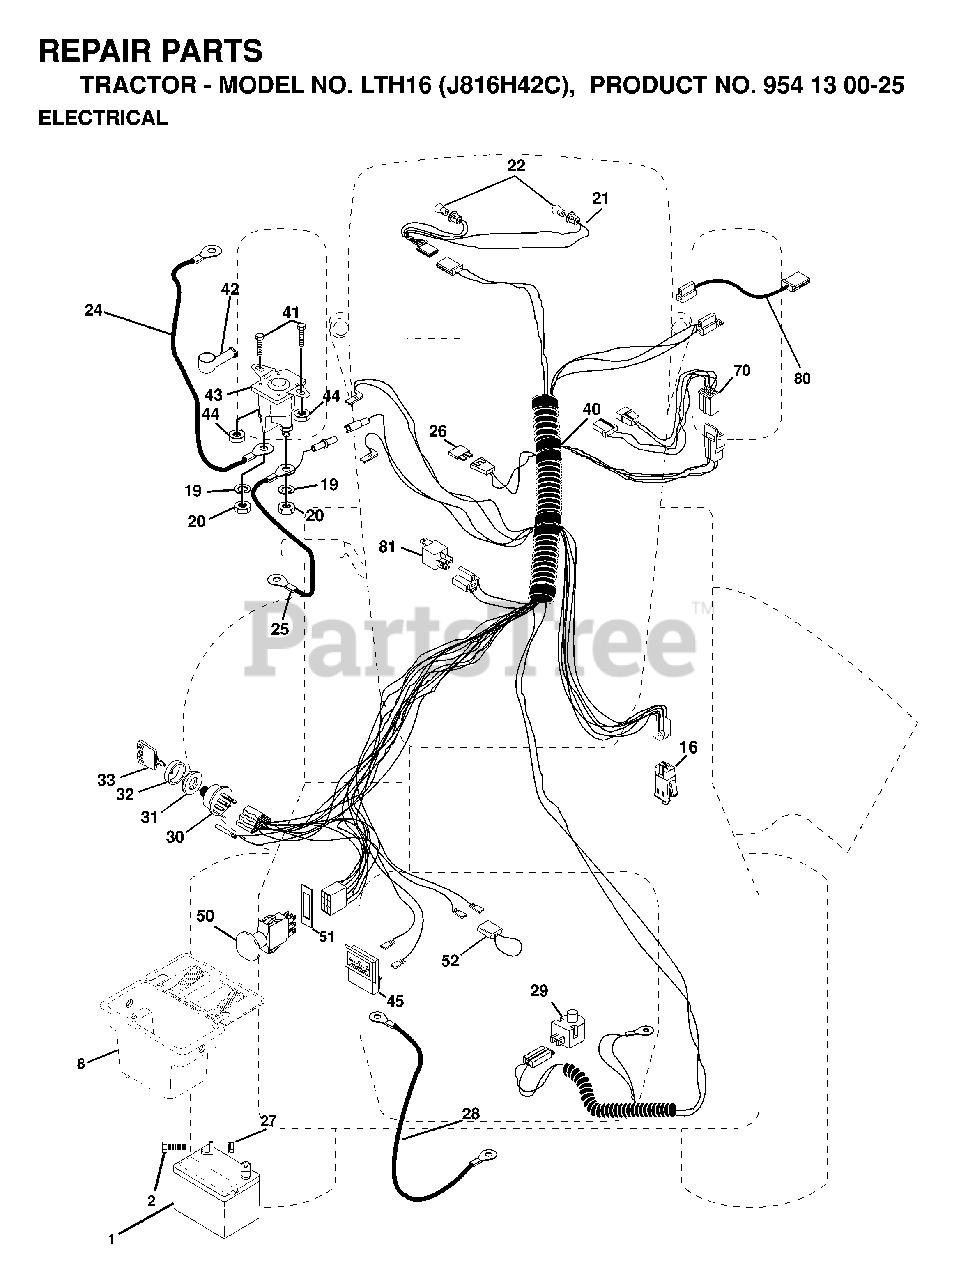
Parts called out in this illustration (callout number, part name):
1	BATTERY 12 VOLT 25 AMP
8	CASE BATTERY MECH HINGE
16	SWITCH INTERLOCK
19	LOCKWASHER
20	NUT
21	HARNESS ASM HDLIG
22	LIGHTBULB
24	BATTERY CABLE GT
25	CABLE BATTERY
27	NUT
28	CABLE T
29	PLUNGER SWITCH (COLOR:OLIVE)
30	SWITCH.IGNITION.4.POSITION
31	NUT IGNITION
32	COVER SWITCH KEY
40	HARNESS.IGNITION
42	TERMINAL COVER
43	SOLINOID
50	SWITCH PTO 3 PDT
51	RETAINING RING
52	WIRE PROTECTION LOOP
80	HARNESS, CLUTCH
81	RELAY.ASSY.T
